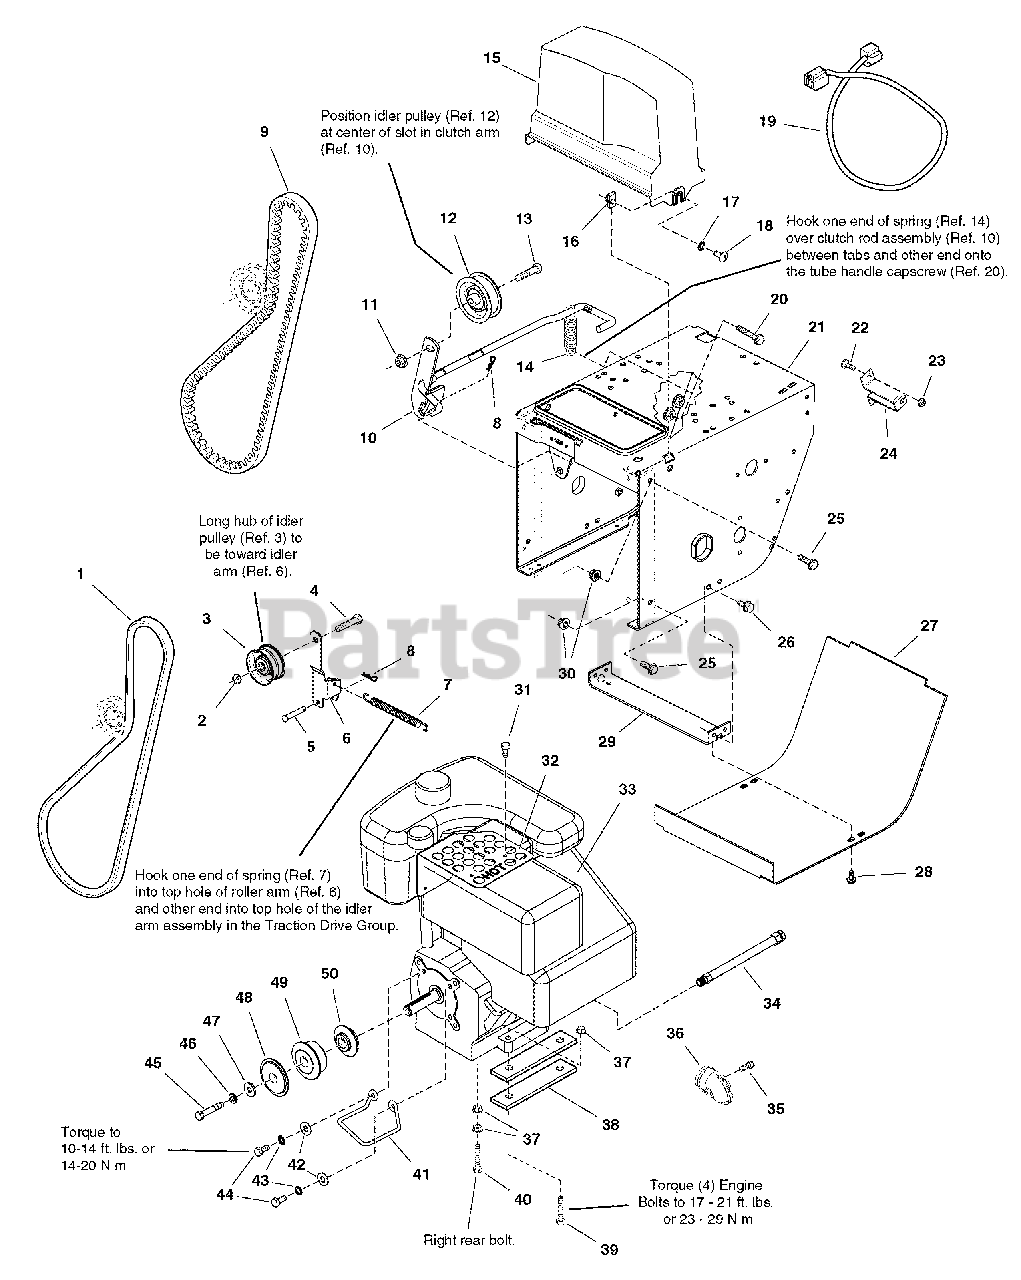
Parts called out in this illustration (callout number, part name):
1	MV-BELT, 3L
2	NUT, Hex, Toplock, Jam, 3/8-16
3	PULLEY, Idler
4	SCREW, Hex Head, 3/8-16 x 1-1/2
5	PIN, Flat Head Drilled
6	ARM, Idler, 5-3/4 LG
7	SPRING, Extension
8	PIN, Quick
10	ROD AND ARM ASSEMBLY, Clutch, Brake
11	NUT, Hex Flange, 3/8-16 Whiz Lock Large
12	PULLEY, Idler
13	CAPSCREW, Hex Whiz Lock Flange, 3/8-16 x 1-3/4
14	SPRING, Extension, 4-1/4 Long
15	COVER, Belt
16	NUT, Speed, 5/16-18, Lug Type
17	LOCKWASHER, External Tooth, 5/16
18	SCREW, Truss head Slotted, 5/16-18 x 3/4
19	CORD, Electric Extension
20	CAPSCREW, Hex Head, 5/16-18 x 1-1/2 G5
21	FRAME ASSEMBLY, Chain/Tube Handles
22	CARRIAGE BOLT, 1/4-20 x 3/4 G5
23	NUT, Hex KEPS, 1/4-20, Conical Washer
24	SUPPORT, Clutch Cable, 16GA
25	SCREW, Hex Whiz Lock Flange, 5/16-18 x 3/4
26	CAPSCREW, Hex Washer Head Taptite, 5/16-18 x 3/4
27	COVER, Bottom Frame, 20GA
28	SCREW, Hex Washer Head Taptite, 1/4-20 x 1/2
29	SUPPORT, Tie Bar
30	NUT, Hex Flange, 5/16-18, Whiz Lock Large
31	SCREW, Hex Washer Head Taptite, #10-24 x 1/2
32	GUARD, Muffler, 18GA
34	HOSE, Oil Drain, w/Fittings
35	SCREW, Muffler Deflector
36	DEFLECTOR, Rain Guard, B&S Snow Muffler
37	NUT, Hex Flange, 5/16-18, Whiz Lock Small
38	SUPPORT, Engine Riser, 3/8" Thick, 1-1/4 x 4-31/50
39	CAPSCREW, Hex Whiz Lock Flange, 5/16-18 x 2-1/4
40	CAPSCREW, Hex Head, 5/16-18 x 2-1/2 G5
42	WASHER, 5/16
43	LOCKWASHER, Spring, 5/16
44	CAPSCREW, Hex Head, 5/16-24 x 3/4 G5
45	CAPSCREW, Hex Head, 3/8-24 x 1-1/2 G8
46	LOCKWASHER, Spring, 3/8
47	WASHER, 3/8
48	PULLEY, Engine Outside, Powdered Metal
49	PULLEY, Engine Middle, Powdered Metal
50	PULLEY, Half Powdered Metal
